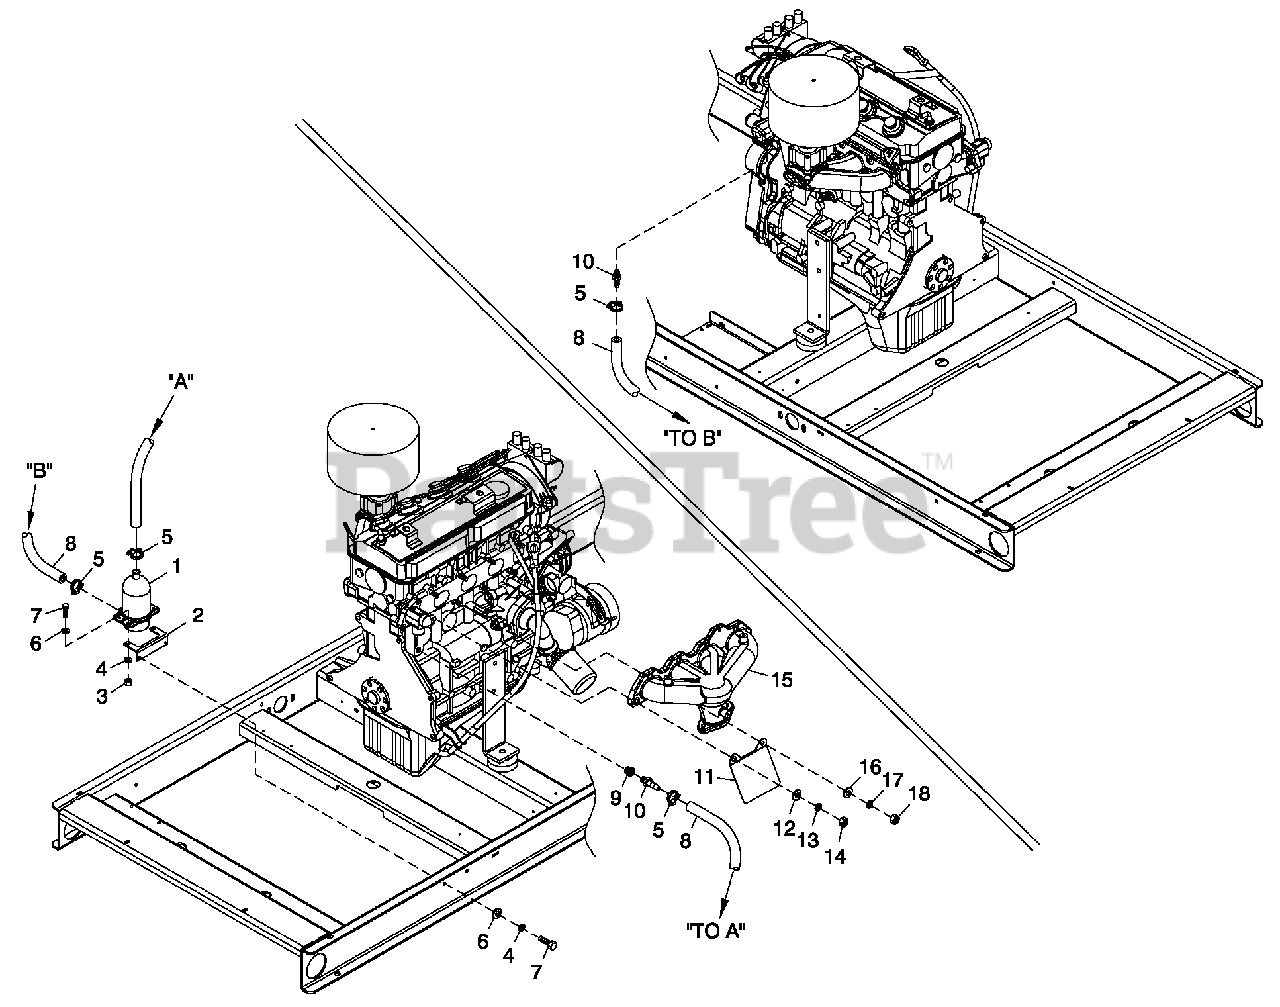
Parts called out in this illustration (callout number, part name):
1	HEATER BLOCK 1500W 120V
2	BRACKET HEATER W/WELDNUTS
3	NUT HEX M6 X 1.0 G8 YEL CHR
4	WASHER LOCK M6-1/4
5	CLAMP HOSE #8 .53-1.00
6	WASHER FLAT 1/4-M6 ZINC
7	SCREW HHC M6-1.0 X 20 G8.8
8	HOSE COOL 5/8 ID 20R3 (66" LG)
9	ADAPTER 3/8 BSPT M X 3/8 NPT F
10	BARBED STR 3/8 NPT X 5/8
11	SHIELD HEAT WATER INLET
12	WASHER FLAT 3/8-M10 ZINC
13	WASHER LOCK M10
14	NUT HEX M10-1.25 G8 YEL CHR
15	MANIFOLD EXHAUST (MACHINED)
16	WASHER FLAT 5/16-M8 ZINC
17	WASHER LOCK M8-5/16
18	NUT HEX M8-1.25 G8 CLEAR ZINC
